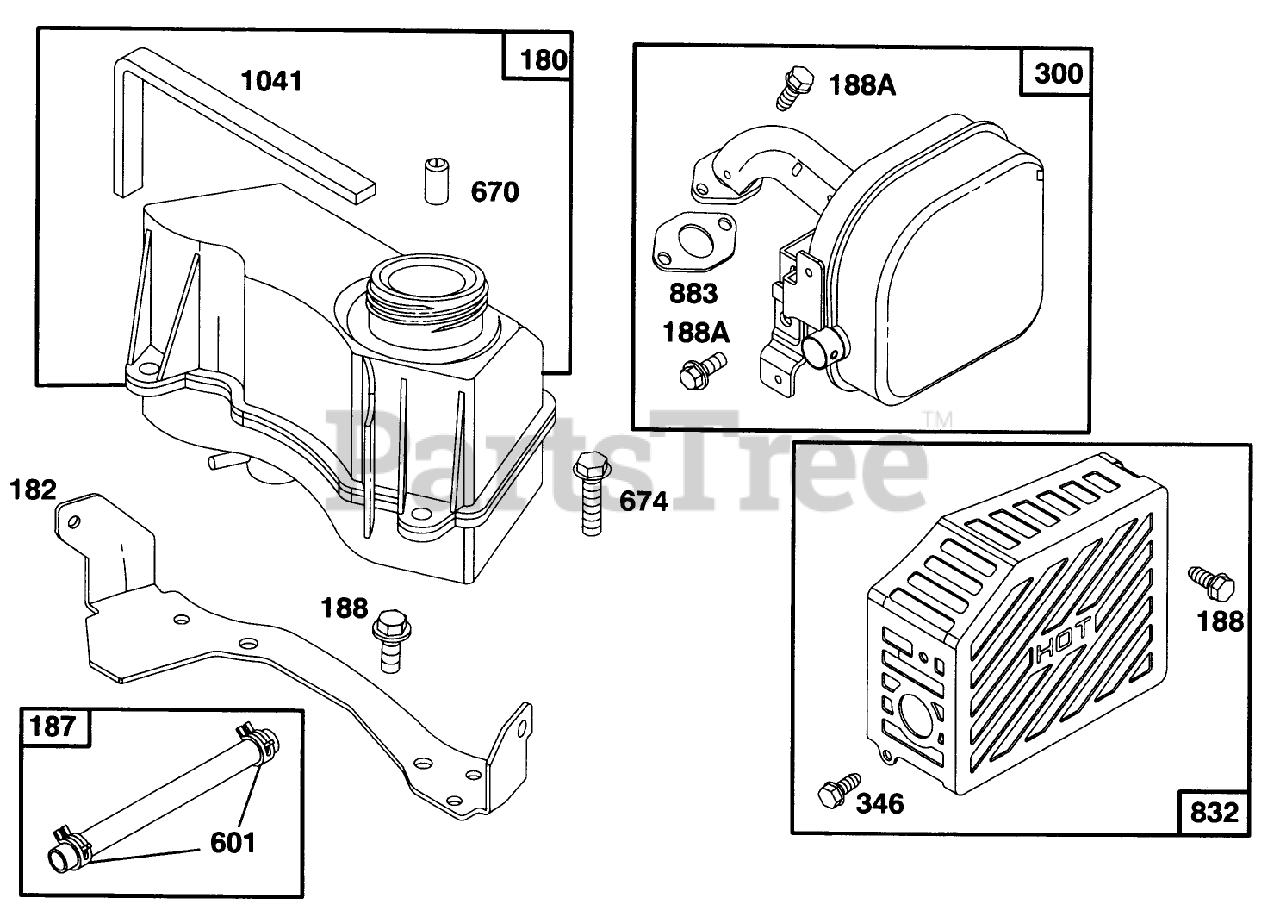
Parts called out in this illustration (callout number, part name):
187	BRIGGS 296004
188A	SCREW - HEX HEAD
300	MUFFLER - EXHAUST
346	SCREW - SELF-TAPPING
670	SPACER
674	SCREW - HEX HEAD
